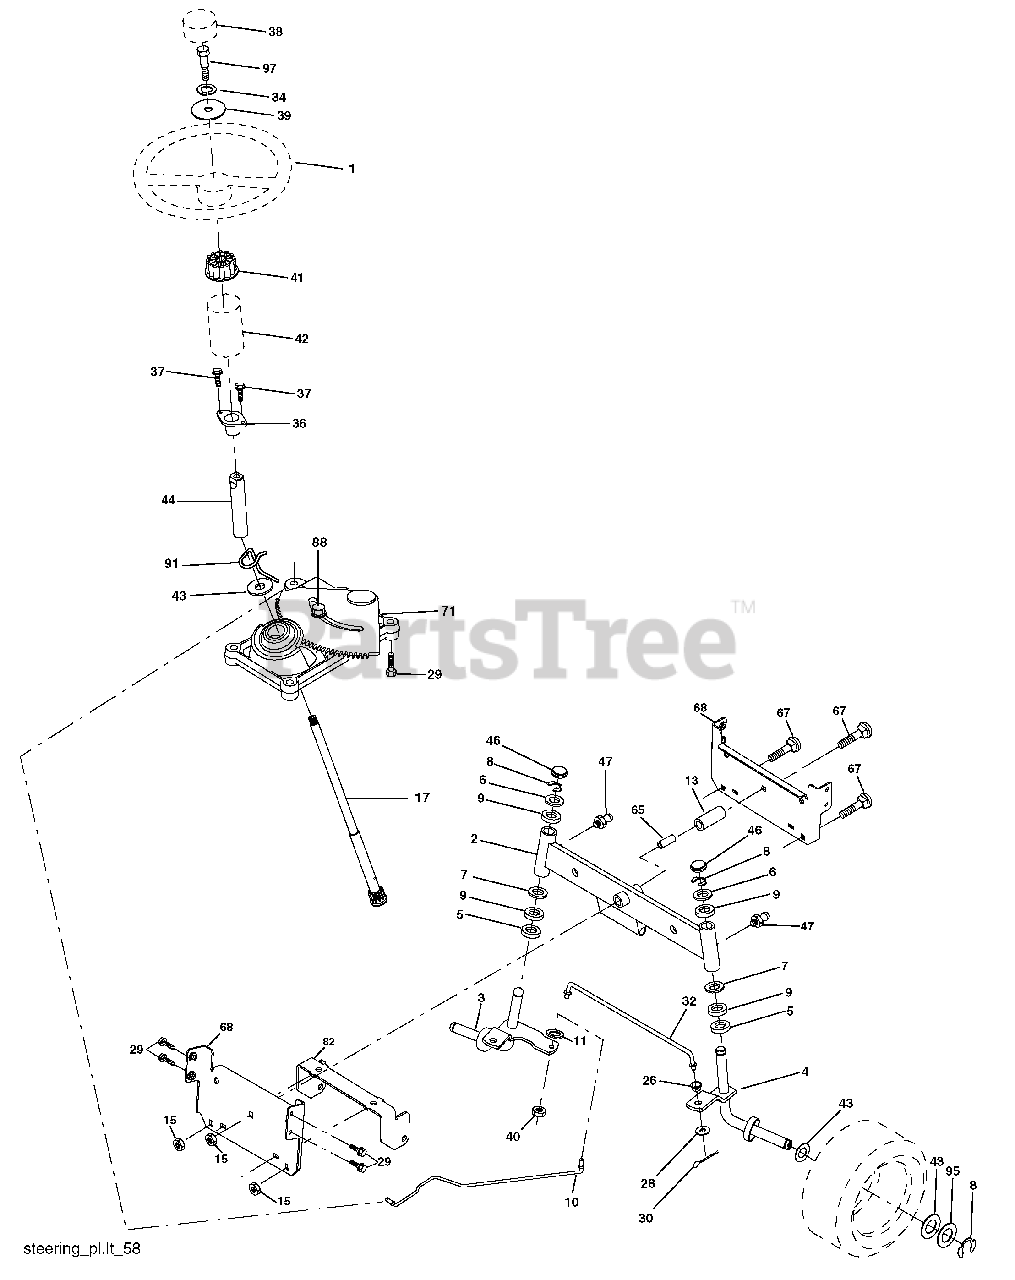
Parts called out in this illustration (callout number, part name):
1	Wheel Steering
2	Axle Asm
3	Spindle Asm LH
4	Spindle Asm RH
5	Bearing Race Thrust Harden
6	Washer 25/32 x 1-5/8 x 16 Ga.
7	Washer 27/32 x 1-1/4 x 16 Ga.
8	Ring Klip #t5304-75
9	Bearing Col Strg Blk
10	Link Drag
11	Washer Lock Hvy Hlcl Spr 3/8
13	Spacer earing Axle Front
15	Hexfl ange Lock
17	Shaft Asm Strg
26	Bushing Link Drag Blk LR
28	Washer 13/32 x 7/8 x 16 Ga.
29	Screw 3/8-16 x 3/4
30	Pin Cotter 1/8 x 3/4 Cad
32	Rod Tie Wire Form 19 75 Mech
34	Washer Lock Hvy Hlcl Spr 5/16
36	Bushing Strg 5/8 Id Dash
37	Screw
38	Cap Wheel Steer Ayp
39	Washer 11/32 ID x 2-3/8 OD x 12 Ga.
40	Nut Crownlock 3/8-24
41	Adaptor Wheel Strg
42	Boot Dash Mtl Steering Blk
43	Washer 25/32 x 1 1/4 x 16 Ga.
44	Extension Steering
46	Cap Spindle Fr Top Blk
47	Fitting Grease
65	Spacer Brace Axle
67	Bolt RDHD SQNK 3/8-16 x 2-1/4
68	Brace Axle
71	Steering Asm.
82	Bracket Susp Chassis Front
88	Bolt Shoulder 7/16-20
91	Clip Steering
95	Washer Harden .793 x 1.637 x 060
97	Bolt 5/16-18 unc x 4"L Hlcl Spr. 5/16
